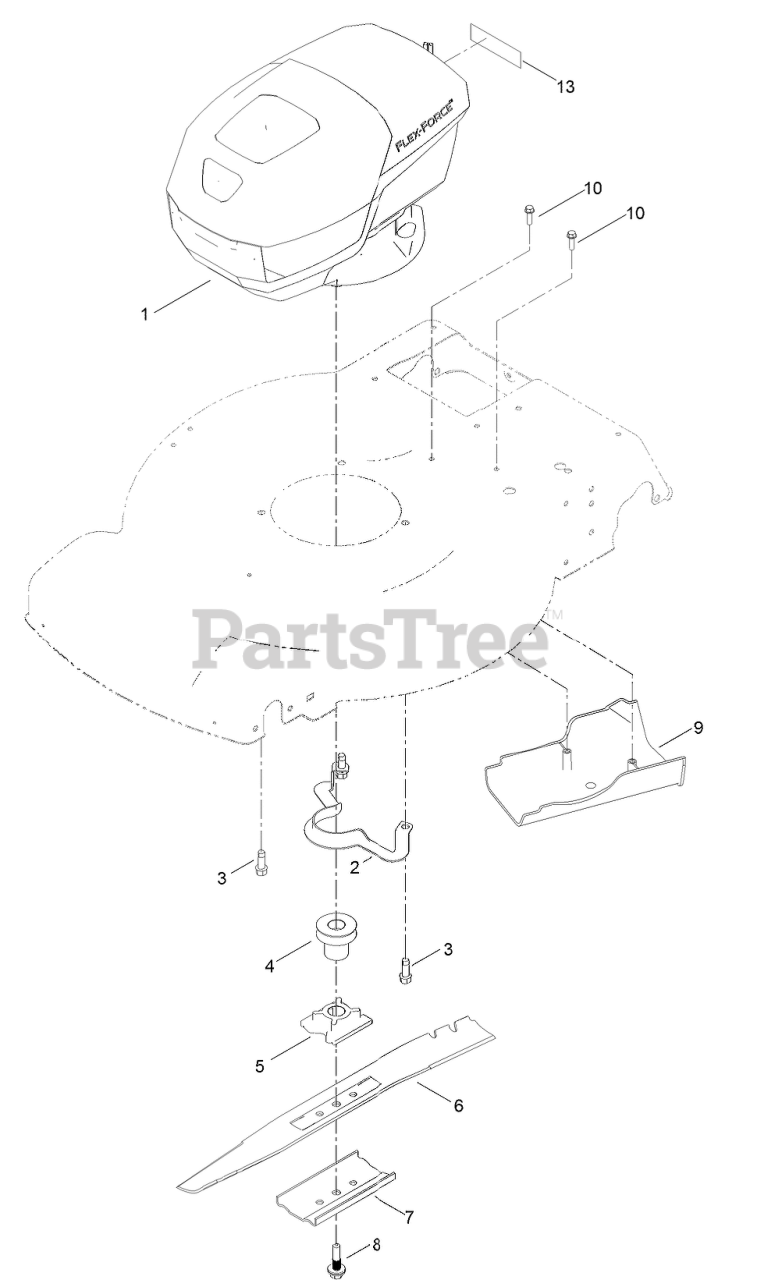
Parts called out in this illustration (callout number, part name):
1	MOTOR MODULE (60V)
2	GUIDE-BELT
3	SCREW-TAPTITE
4	PULLEY
5	RETAINER-BLADE
7	SUPPORT-BLADE
8	BOLT-BLADE
9	COVER-BELT
10	SCREW-PLASTITE, HWH
13	DECAL-WARNING
